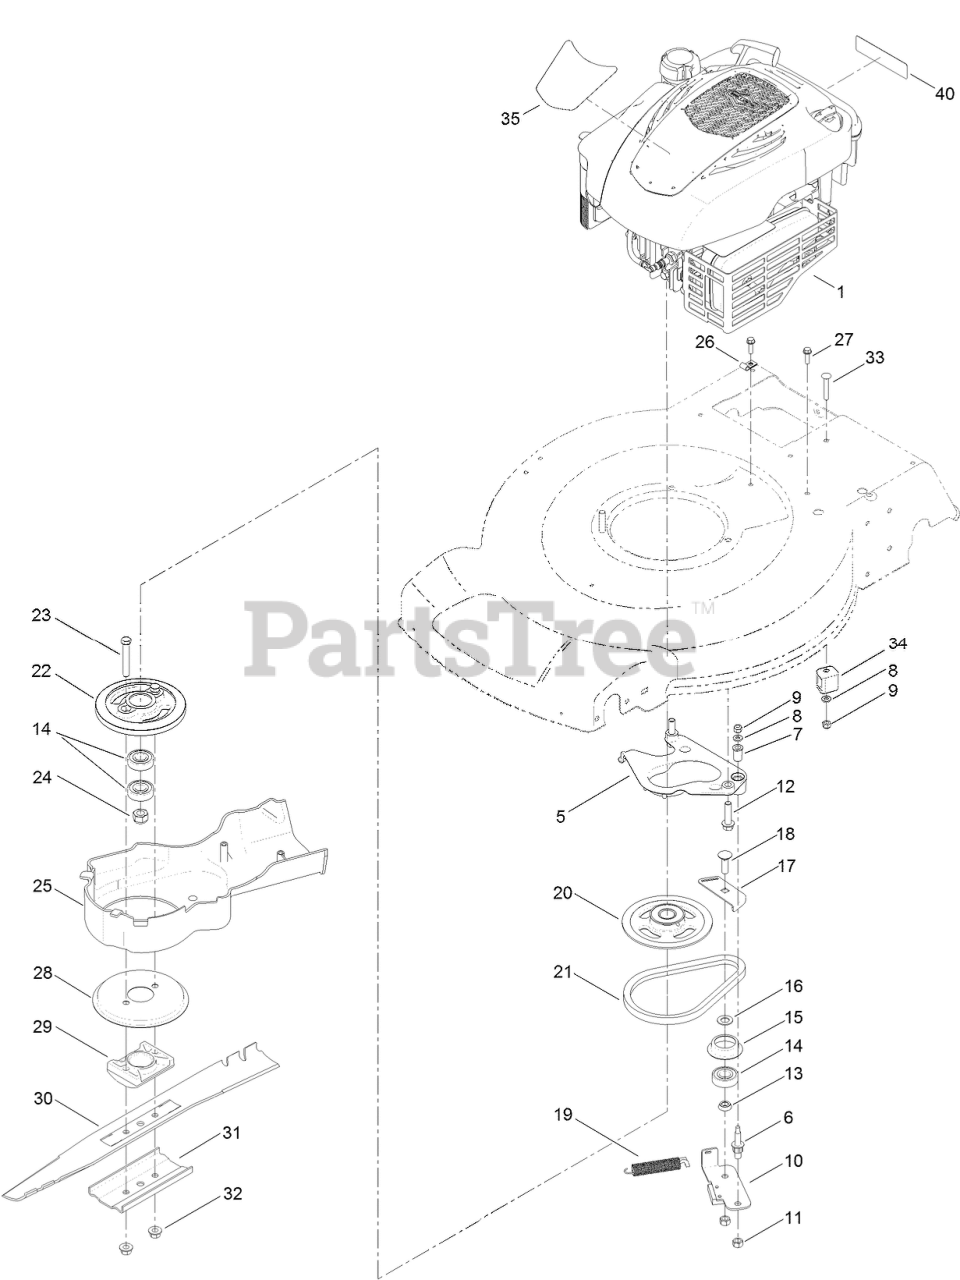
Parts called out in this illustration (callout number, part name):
5	PLATE-ANCHOR
6	BOLT-SHOULDER
7	BUSHING
8	WASHER-FLAT
9	NUT-LOCK, NI
10	PLATE-BRAKE
11	NUT-HEX
12	SCREW-HWH
13	SPACER-BEARING
14	BEARING-BALL
15	RETAINER-BELT
16	WASHER-PLAIN
17	PLATE-GUIDE
18	BOLT-CARR
19	SPRING-TENSION, BRAKE
20	PULLEY
21	BELT
22	DRUM
23	SCREW-HH
24	NUT-HEX
26	CLIP-CLOSED, INSULATED
27	SCREW-HWH
28	DISC
29	SUPPORT-BLADE
30	BLADE-22 INCH
31	SUPPORT-BLADE
32	NUT-LOCK
33	SCREW-CARR
34	ANCHOR-CABLE
35	DECAL-SHROUD
40	DECAL-ARRESTER, SPARK
